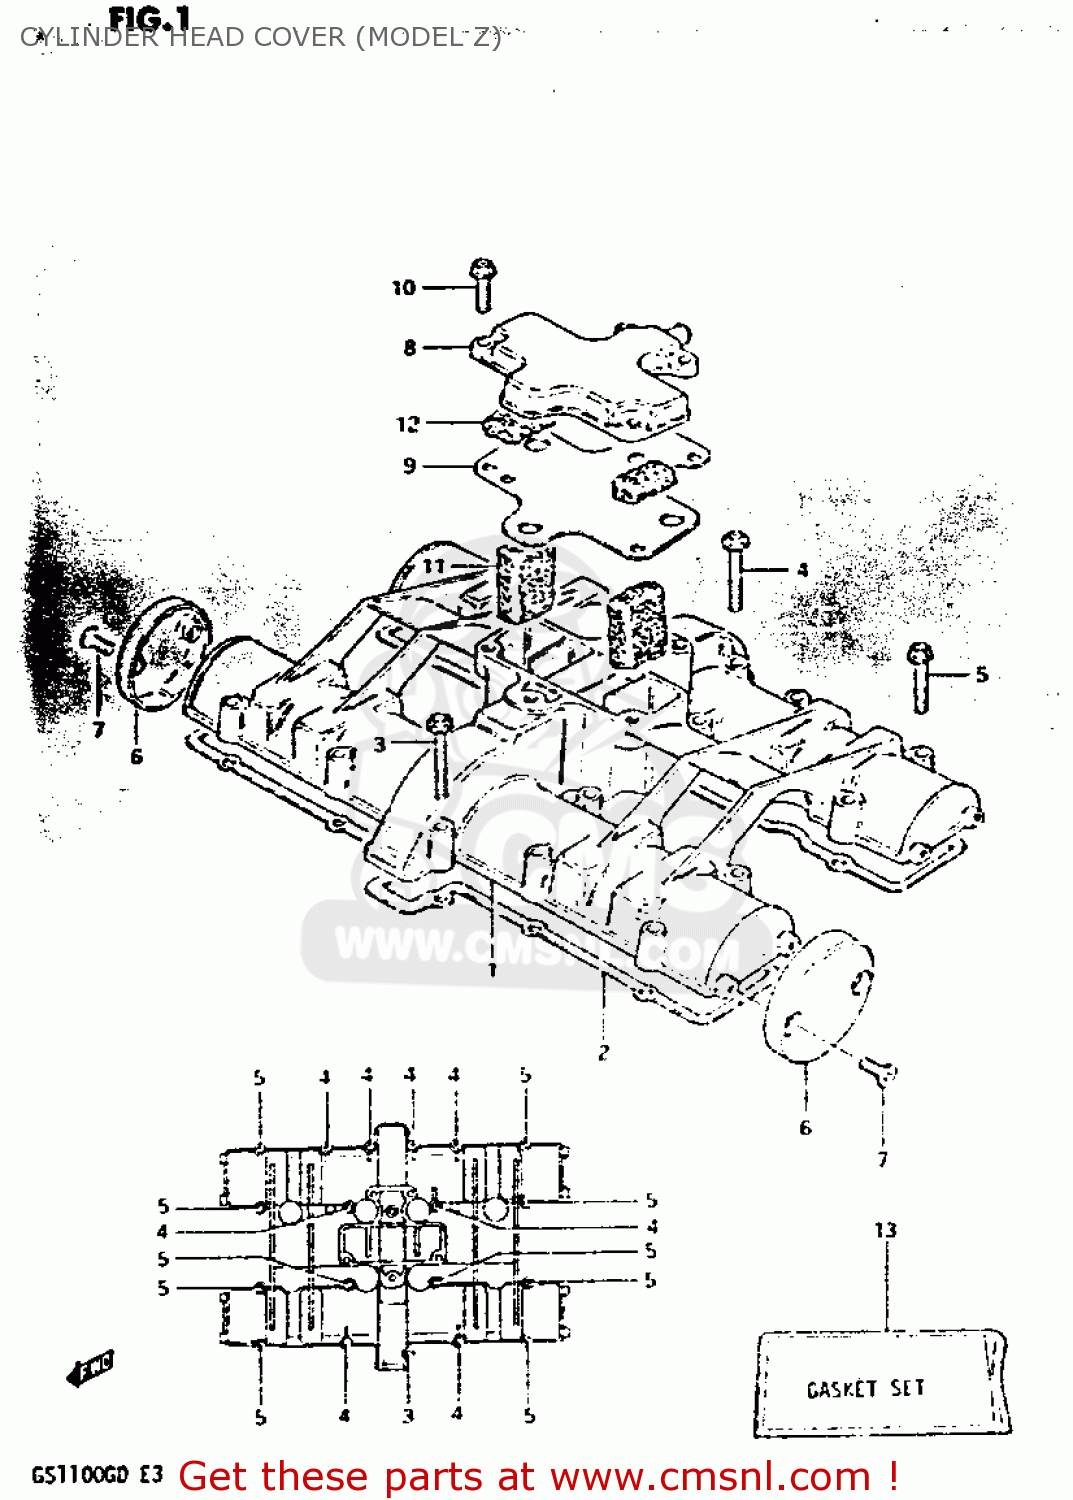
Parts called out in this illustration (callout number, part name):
1	COVER,CYLINDER HEAD
2	GASKET,CYL HEAD COVER (NAS)
3	BOLT,UNDER
4	BOLT
5	BOLT 6X35
6	CAP,CYLINDER HEAD COVER
7	SCREW(5X12)
8	COVER,BREATHER
9	GASKET (MCA)
10	BOLT 6X25
11	COVER,BREATHER
12	SEPARATOR,OIL BREATHER
13	GASKET SET
